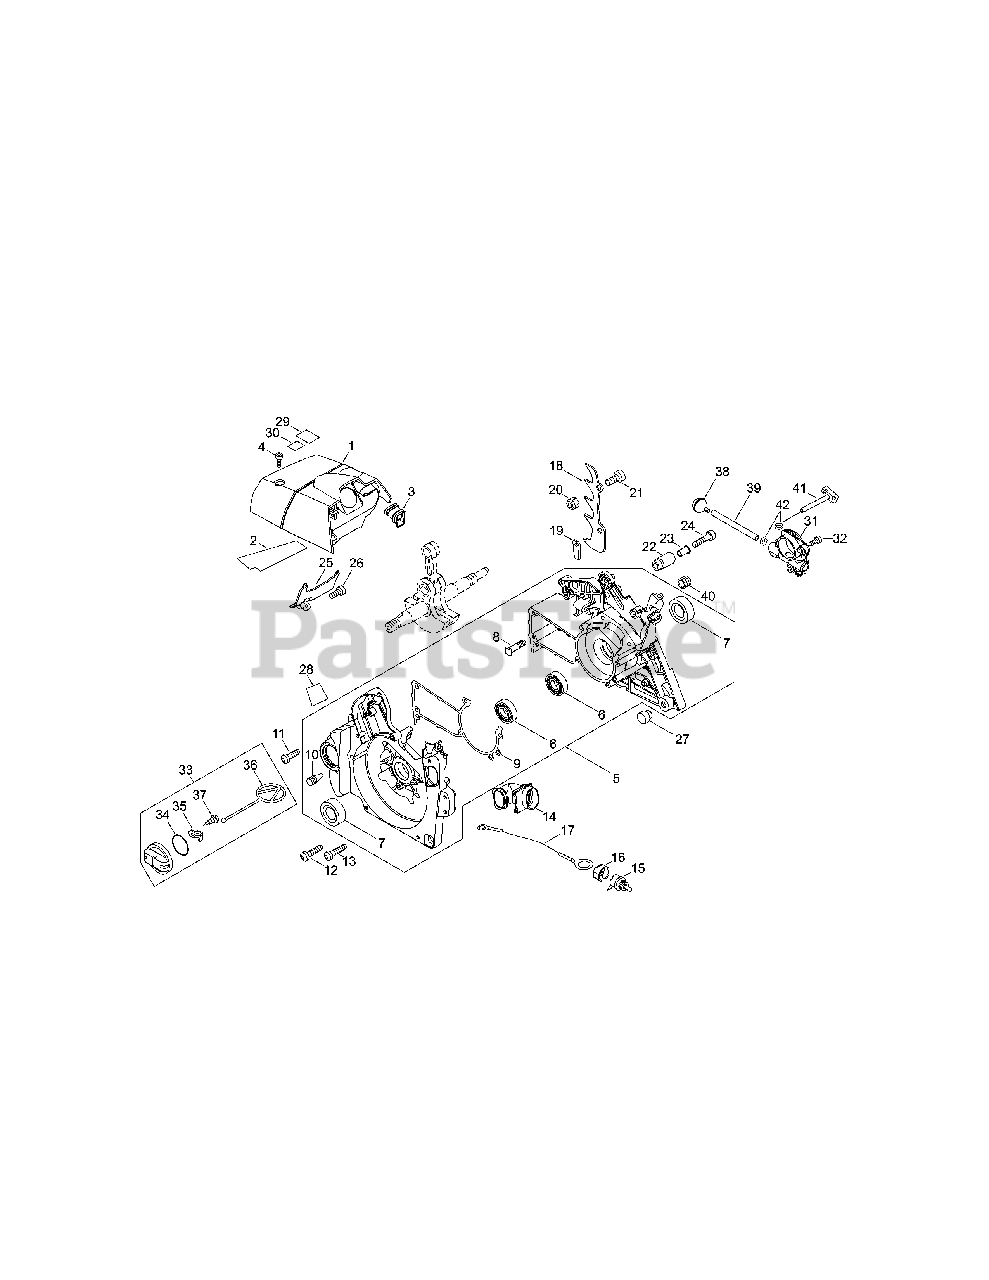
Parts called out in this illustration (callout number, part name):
1	COVER,CYLINDER
2	WASHER,SQUARE
3	PIPE, INTAKE
4	BOLT, TORX 5
5	CRANK CASE SET
6	BEARING BALL
7	SEAL,OIL 15
8	BOLT,8
9	GASKET,CRANKCASE
10	VALVE, CHECK
11	BOLT, TORX 5
12	BOLT, TORX 5
13	BOLT, TORX 5
14	PIPE, INTAKE
15	SWITCH, ON OFF
16	CASE,SWITCH
20	NUT, LOCK 5
21	BOLT, TORX 5
22	CATCHER,CHAIN
23	COLLAR,5
24	BOLT, TORX 5
25	GUIDE,AIR
26	BOLT, TORX 5
27	CUSHION
29	LABEL,CAUTION
30	LABEL,CAUTION
31	AUTO-OILER ASSEMBLY
32	BOLT, TORX 4
33	CAP, OIL
34	O-RING 28
35	RETAINER, LINK
36	LINK
37	SCREW 3×8
38	STRAINER, OIL
39	PIPE, OIL
40	GROMMET
41	PIPE
